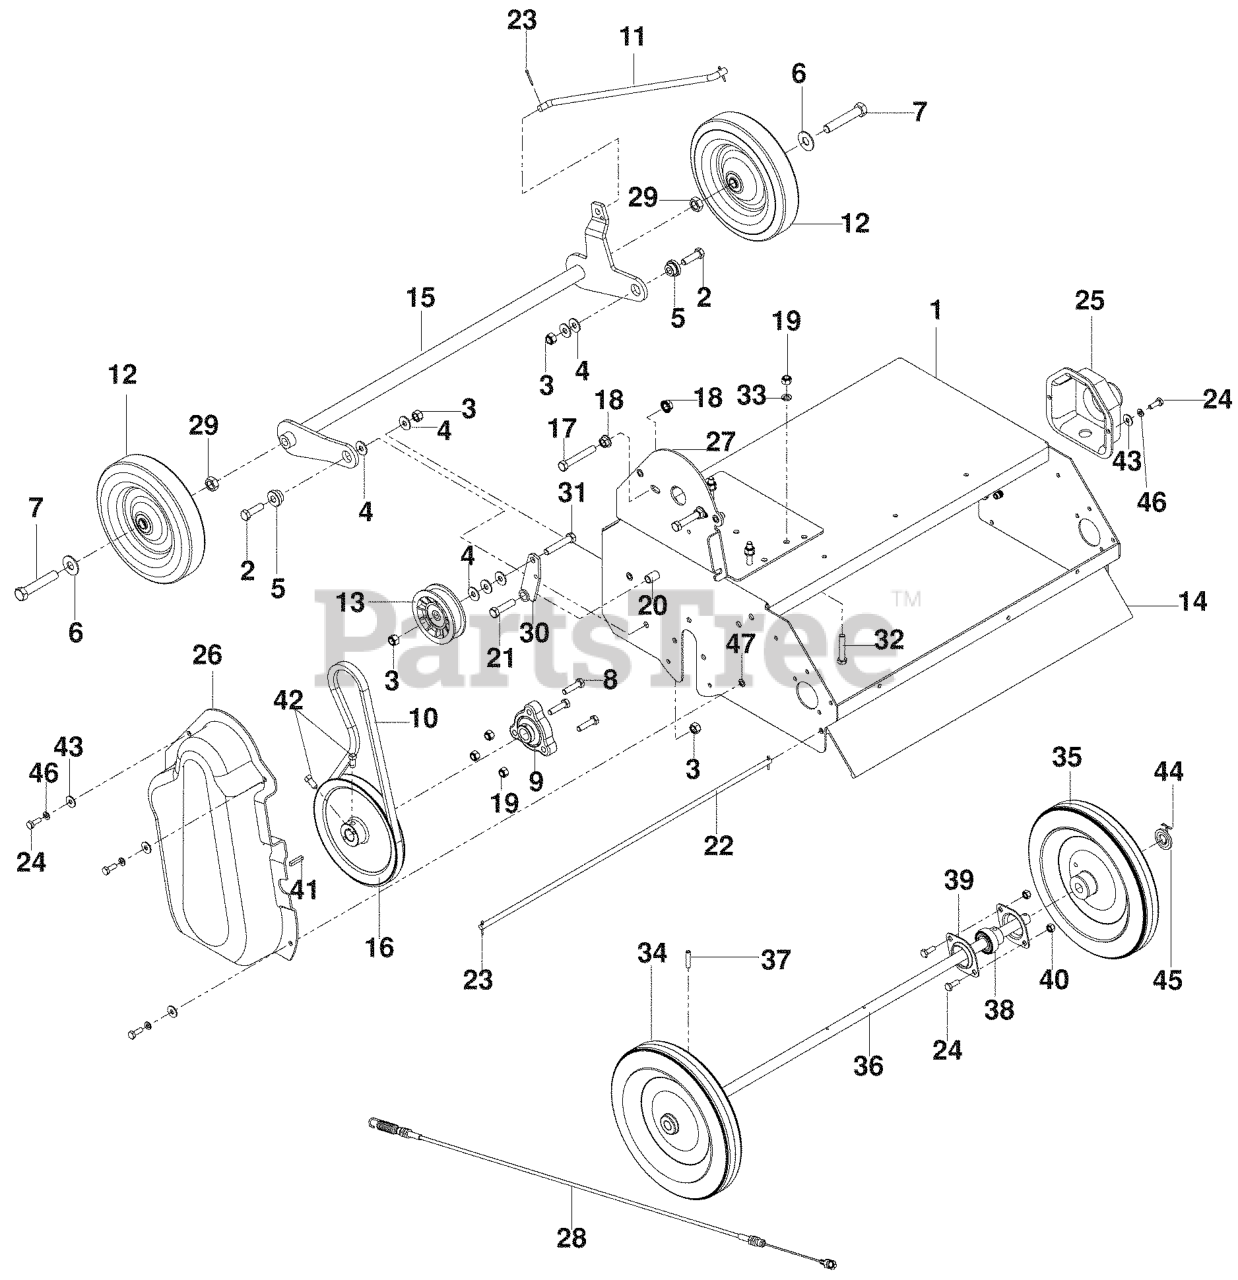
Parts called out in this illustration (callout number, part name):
1	WLDMT, BODY - ORANGE DT22
2	HCS 3/8C X 1 1/4 GR5
3	NUT 3/8-16 NYLOC
4	WASHER 5/16 FLAT
5	BUSHING RAKE
6	WASHER 1/2 FLAT
7	HCS 1/2C X 2 3/4
8	HCS 5/16C X 1 1/4
9	BEARING, FLANGED
10	BELT, DRIVE RAKE/SLICER DFS
12	WHEEL 8 X 1 3/4 RAKE
13	PULLEY, IDLER RAKE & ZTR
15	FRONT AXLE
16	PULLEY, MAIN SHAFT
17	HCS 3/8C X 2 1/2
18	NUT 3/8C WHIZ
19	NUT 5/16 NYLOC
20	BEARING, ONLITE RAKE/DT
21	HCS 3/8C X 1 1/2
23	COTTER PIN 3/32 X 3/4
24	HCS 1/4C X 3/4 HCS
25	SHAFT GUARD
26	BELT GUARD
27	BACKING PLATE ORANGE
28	CABLE POWER RAKE
29	NUT 1/2 HEX JAM
30	IDLER ARM - ORANGE
31	HCS 3/8C X 2
32	HCS 5/16C X 1 3/4
33	WASHER.LOCK.HVY.HLCL.SPR.5/16
34	WHEEL 10 X 1 3/4
35	WHEEL 10 X 1 3/4
36	AXLE, REAR
37	PIN ROLL 1/4 X 1-1/8
38	DNB BRACKET C/S LIFT 3/16
39	DNB BRKT UPPER LATCH NONPLATED
40	NUT.1/4-20.HEX.NYLOC.ZD
41	KEY, 3/16 SQUARE
42	SCREW 5/16C X 5/8 SQ HEAD
43	WASHER 1/4 FLAT
44	COTTER PIN
45	WASHER 5/8 FLAT
46	LOCKWASHER 1/4"
47	KNURLED INSERT
